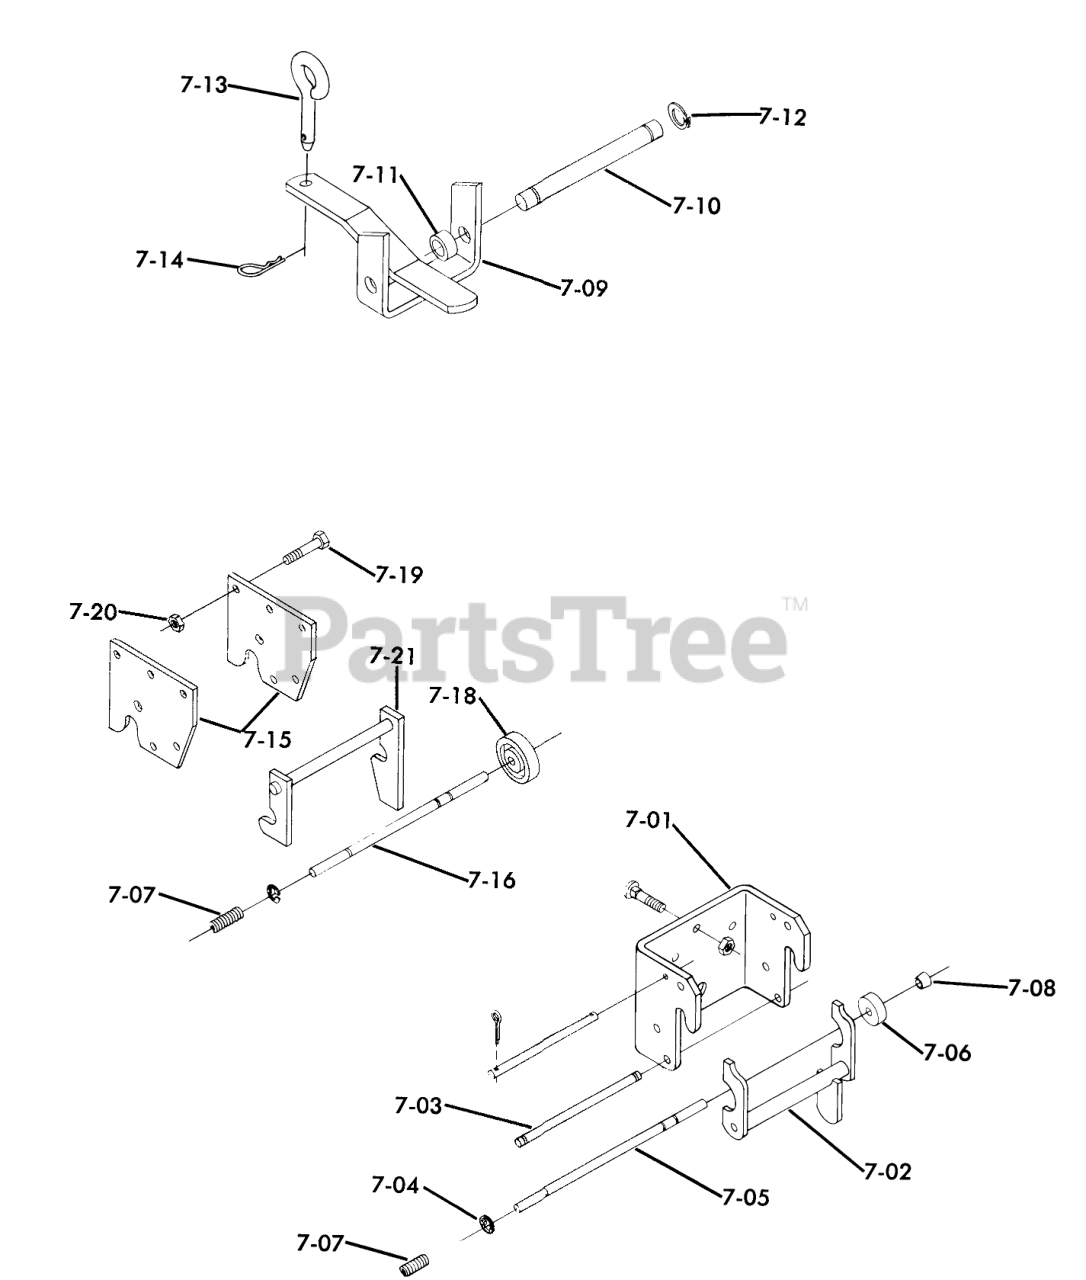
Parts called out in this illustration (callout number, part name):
7-01	Front Hitch
7-02	Assy-Latch
7-03	ROD-LATCH PIVOT
7-04	Lock Rod
7-05	ROD-LOCK
7-07	SPRING
7-08	CAP-ROD, PLUNGER
7-09	Hitch
7-10	PIN-STATIONARY HITCH
7-11	Spacer
7-12	E-RING
7-13	Pin-Tool
7-14	Hairpin Cotter
7-15	Hitch Plate
7-17	ASSY MID HITCH LA R
7-19	BOLT
7-20	Nut
